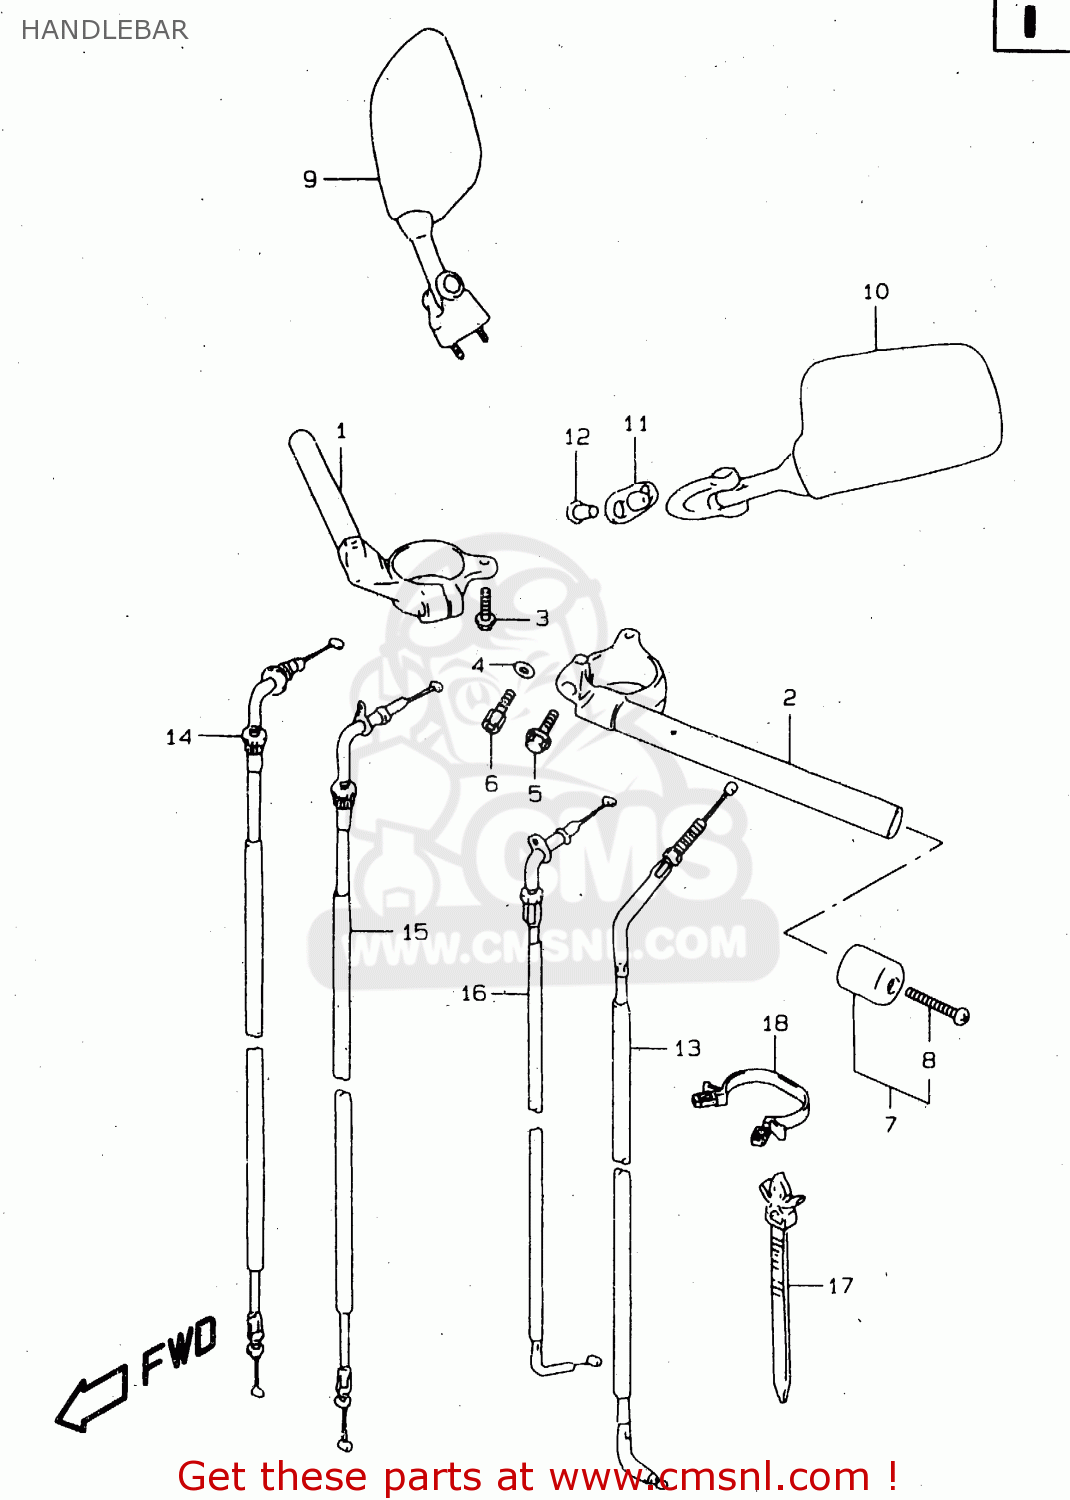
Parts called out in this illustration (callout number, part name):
1	HANDLEBAR,R
2	HANDLEBAR,L
3	BOLT
4	WASHER
5	BOLT(8X30)
6	BOLT(8X30)
7	BALANCER SET,HANDLEBAR
8	SCREW
9	MIRROR ASSY,RR VIEW,R
10	MIRROR ASSY,RR VIEW,L
11	CUSHION,RR VIEW MIRRORR
12	NUT,RR VIEW MIRROR
13	CABLE ASSY,CLUTCH
14	CABLE ASSY,THROTTLE NO.1
15	CABLE ASSY,THROTTLE NO.2
16	CABLE,STARTER
17	CLAMP(L:90)
18	CLAMP
